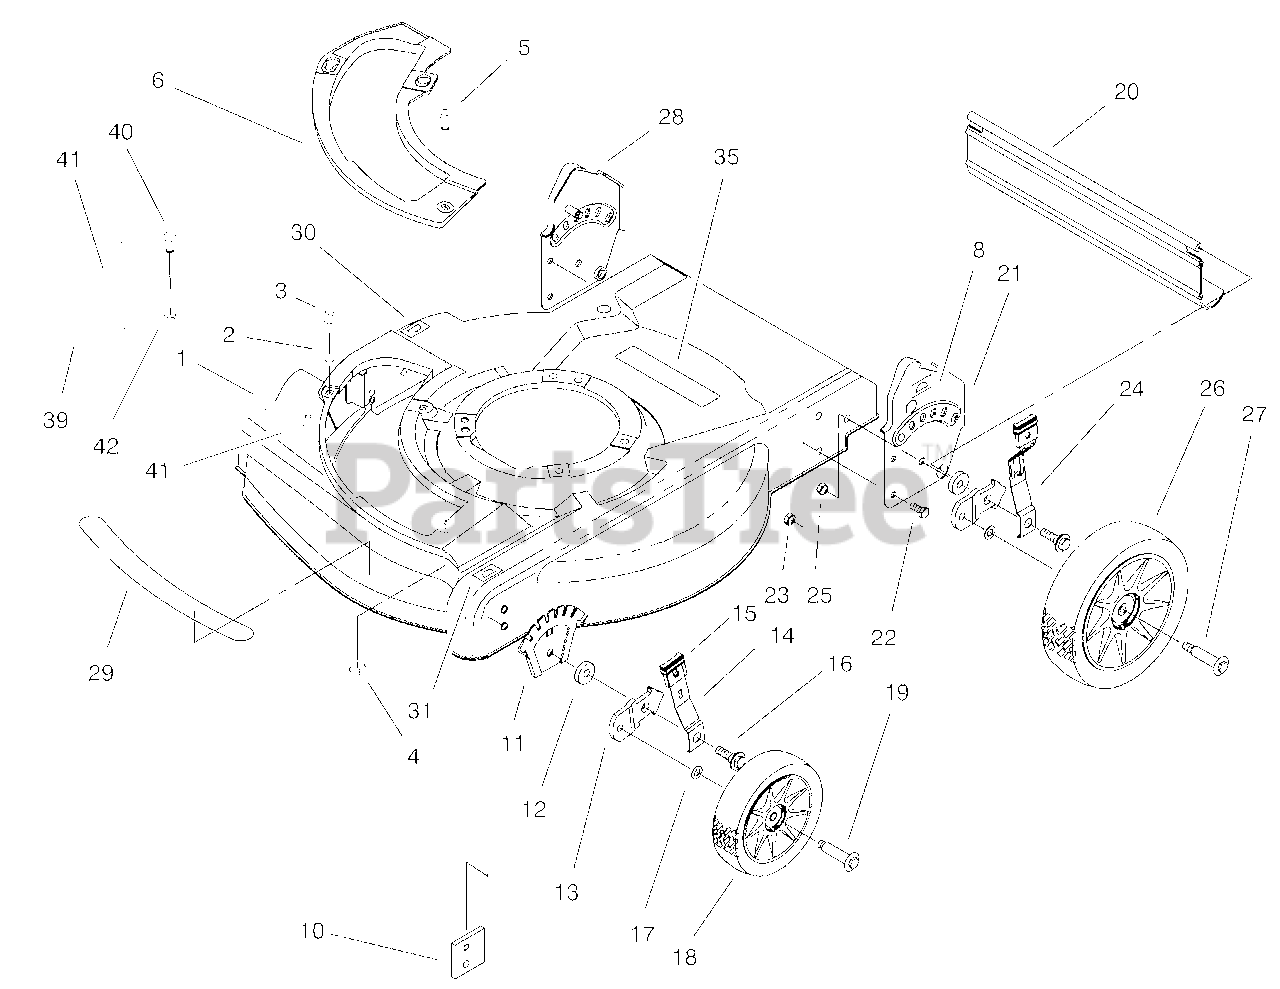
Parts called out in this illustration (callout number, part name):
1	ASM-Hous & Baffle(Mach)
2	Grommet-Plastic
3	Screw-Sems
4	Nut-Cage
5	Screw-HH
6	Plate-Cover
10	Plate-Baffle
11	Plate-Height Adjust
13	Bracket-Wheel Height Adj
14	Spring Arm-Front
15	Knob-Height Adjust
16	Bolt-Shoulder
18	ASM-Wheel & Tire 6"
19	Bolt-Shoulder
20	Shield-Trailing
21	ASM-Handle Brkt
22	Screw-HH
23	Nut-Lock
24	ASM-Spring Arm
25	Nut-Lock
26	ASM-Wheel
27	Bolt-Shoulder
28	RH Handle Bracket ASM
29	Decal-Deck 345vp
30	Decal-HOC
31	Decal-HOC
35	Decal-Danger
39	Guard-Plate
41	Decal-Danger
42	Nut-Lock
